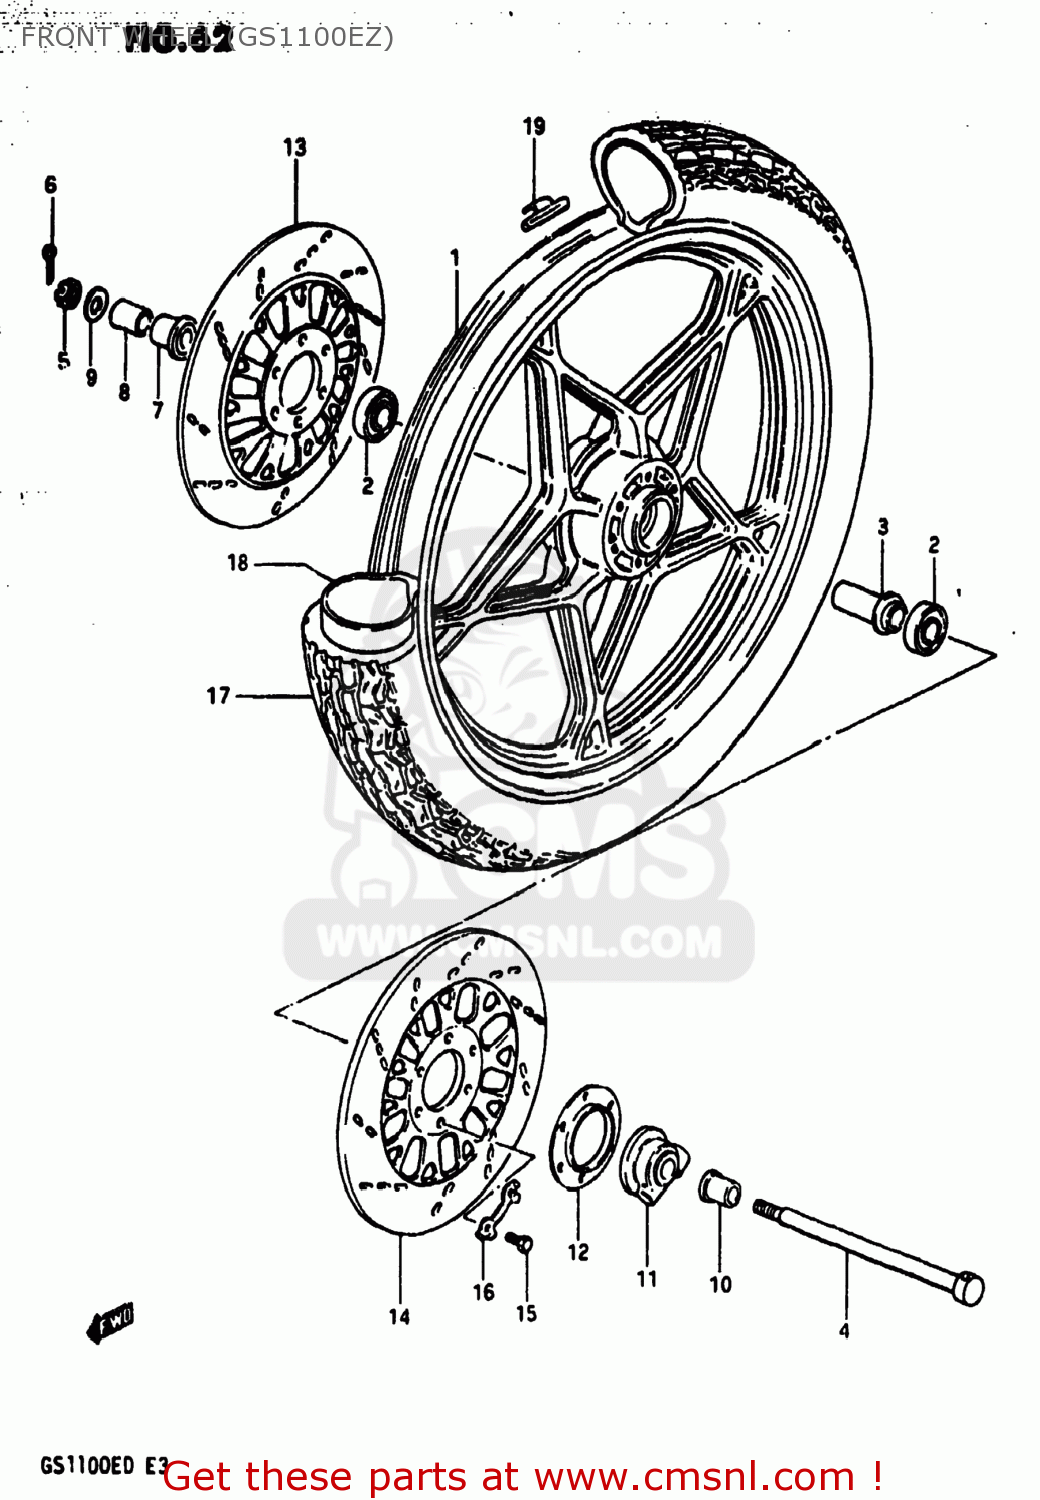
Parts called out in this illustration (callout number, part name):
1	WHEEL, FRONT (19X1.85) (GRAY)
2	BEARING
3	SPACER,FR HUB BEARING
4	AXLE,FR
5	NUT 12MM
6	COTTER PIN
7	SPACER,FR AXLE,R
8	SPACER,FR AXLE,R
9	WASHER
10	SPACER,FR AXLE,L
11	BOX ASSEMBLY,SPEEDOMETER GEAR
12	DUST SEAL,SPEEDOMETER GEAR BOX
13	DISC,FR BRAKE,R
14	DISC,FR BRAKE,L
15	BOLT(8X25)
16	WASHER
17	TIRE,FRONT
18	TUBE,INNER
19	BALANCER,WHEEL
